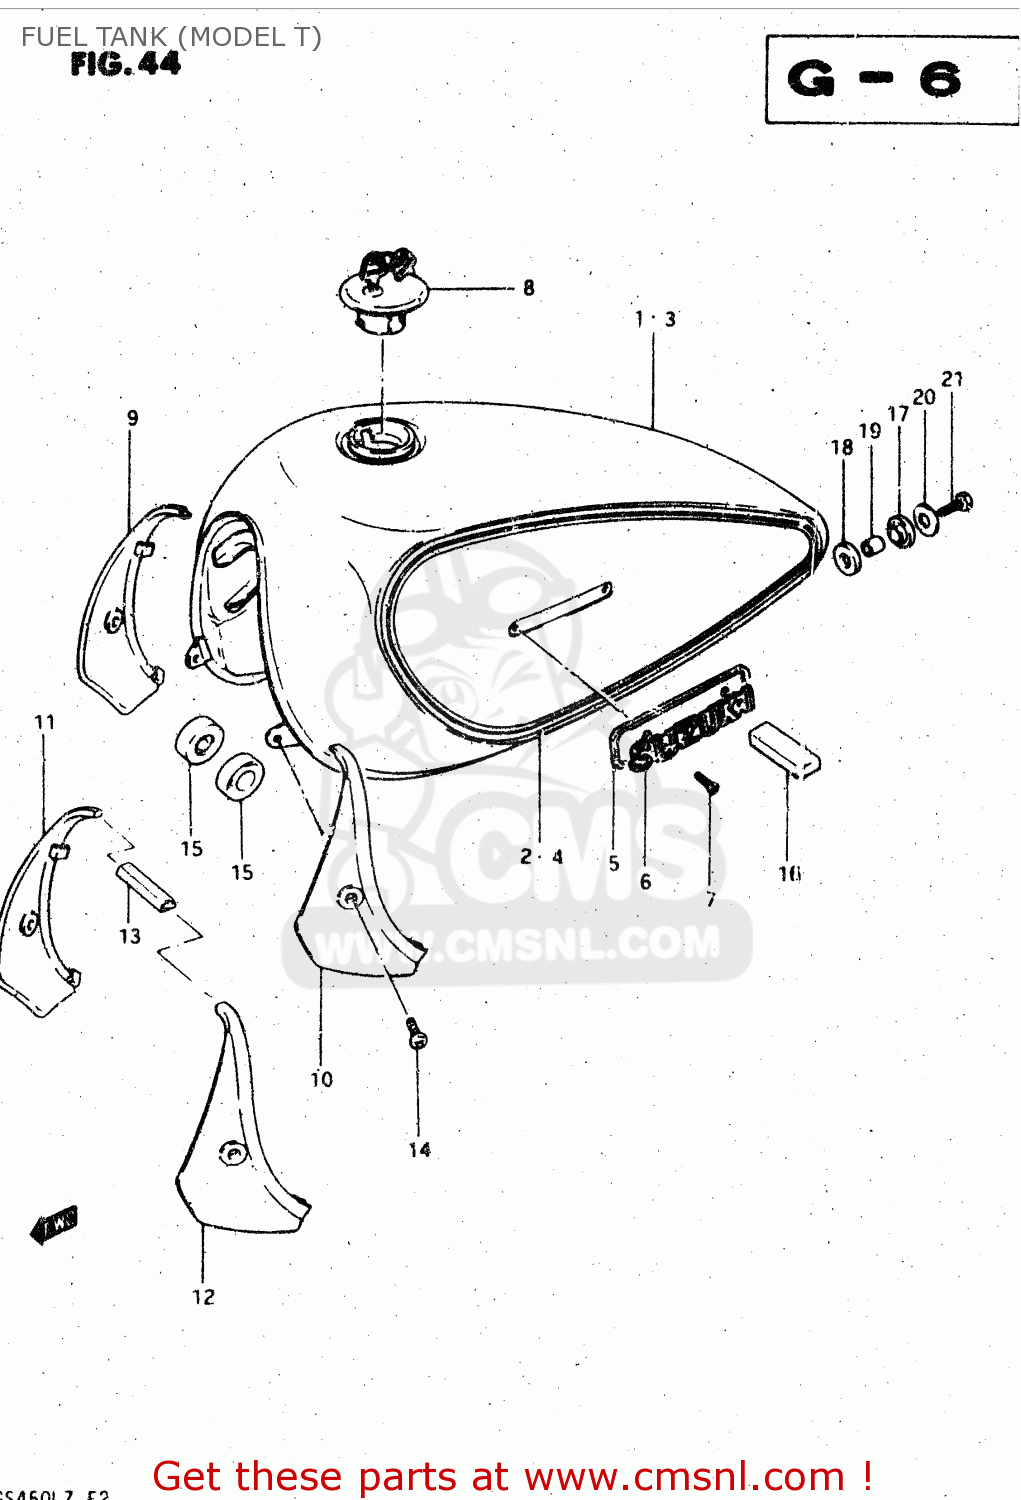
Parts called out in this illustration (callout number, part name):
1	TANK ASSEMBLY,FUEL
2	TAPE SET,FUEL TANK STRIPE
3	TANK ASSEMBLY,FUEL
4	TAPE SET,FUEL TANK
5	CUSHION
6	EMBLEM,FUEL TANK
7	SCREW 3X6
8	CAP SET,FUEL TANK
9	COVER,FUEL TANK
10	COVER,FUEL TANK
11	COVER,FUEL TANK,FRONT,RIGHT
12	COVER,FUEL TANK,FRONT,LEFT
13	TUBE, FRONT
14	SCREW 6X12
15	CUSHION
16	CUSHION
17	CUSHION
18	CUSHION
19	SPACER(8.5X12X19)
20	WASHER (8.5X29X1.6)
21	BOLT (8X30)
